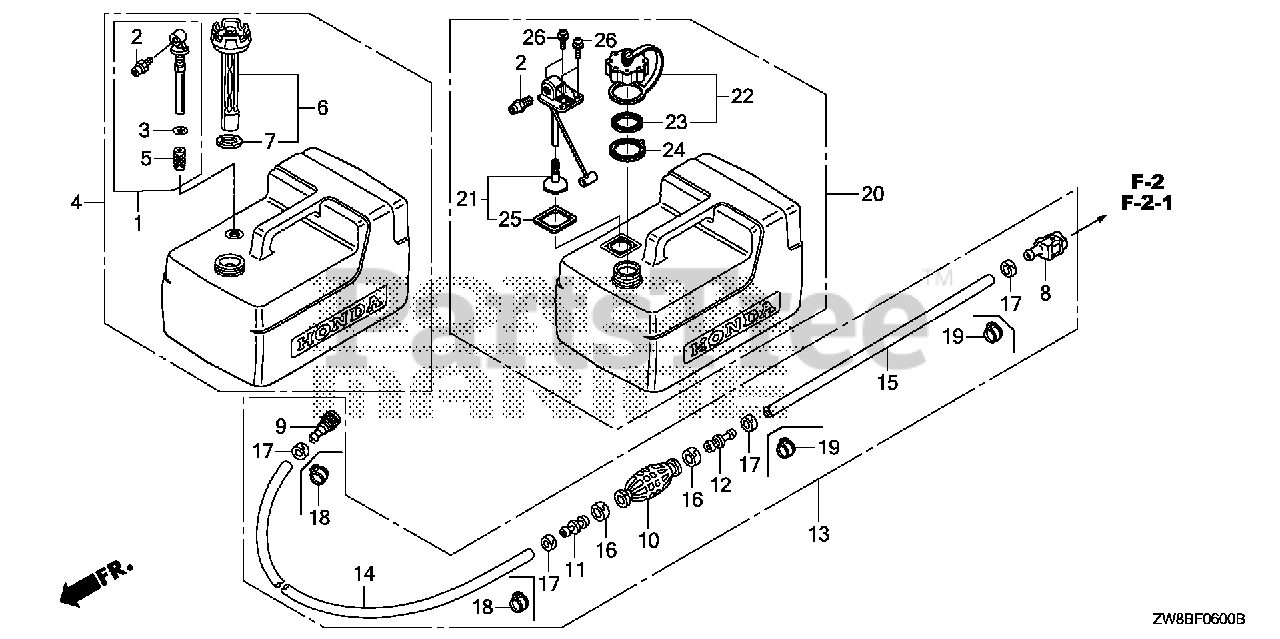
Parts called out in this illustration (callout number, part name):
1	JOINT ASSY., FUEL
2	FITTING, QUICK DISCONNECT Use from Frame SN 1205705.
3	O-RING Use from Frame SN 1300962.
4	TANK ASSY., FUEL
5	FILTER, FUEL
6	CAP, FUEL FILLER
7	GASKET, FUEL CAP
8	CONNECTOR ASSY., FUEL (A)
9	CONNECTOR, FUEL (CONNECTOR TYPE)
10	BULB, PRIMER
11	VALVE, IN.
12	VALVE, OUTLET
13	TUBE ASSY., FUEL
13	TUBE ASSY., FUEL TANK
14	TUBE, FUEL LONG (7.3X2000) (CONNECTOR TYPE)
14	TUBE, FUEL LONG (7.3X2000)
15	TUBE, FUEL SHORT (6.3X500) (CONNECTOR TYPE)
15	TUBE, FUEL SHORT (6.3X500)
15	TUBE, FUEL SHORT
16	BAND, TUBE CLIP (20MM)
17	BAND, TUBE CLIP (12.5MM)
18	CLAMP, FUEL TUBE (CONNECTOR TYPE)
19	CLAMP, FUEL TUBE
